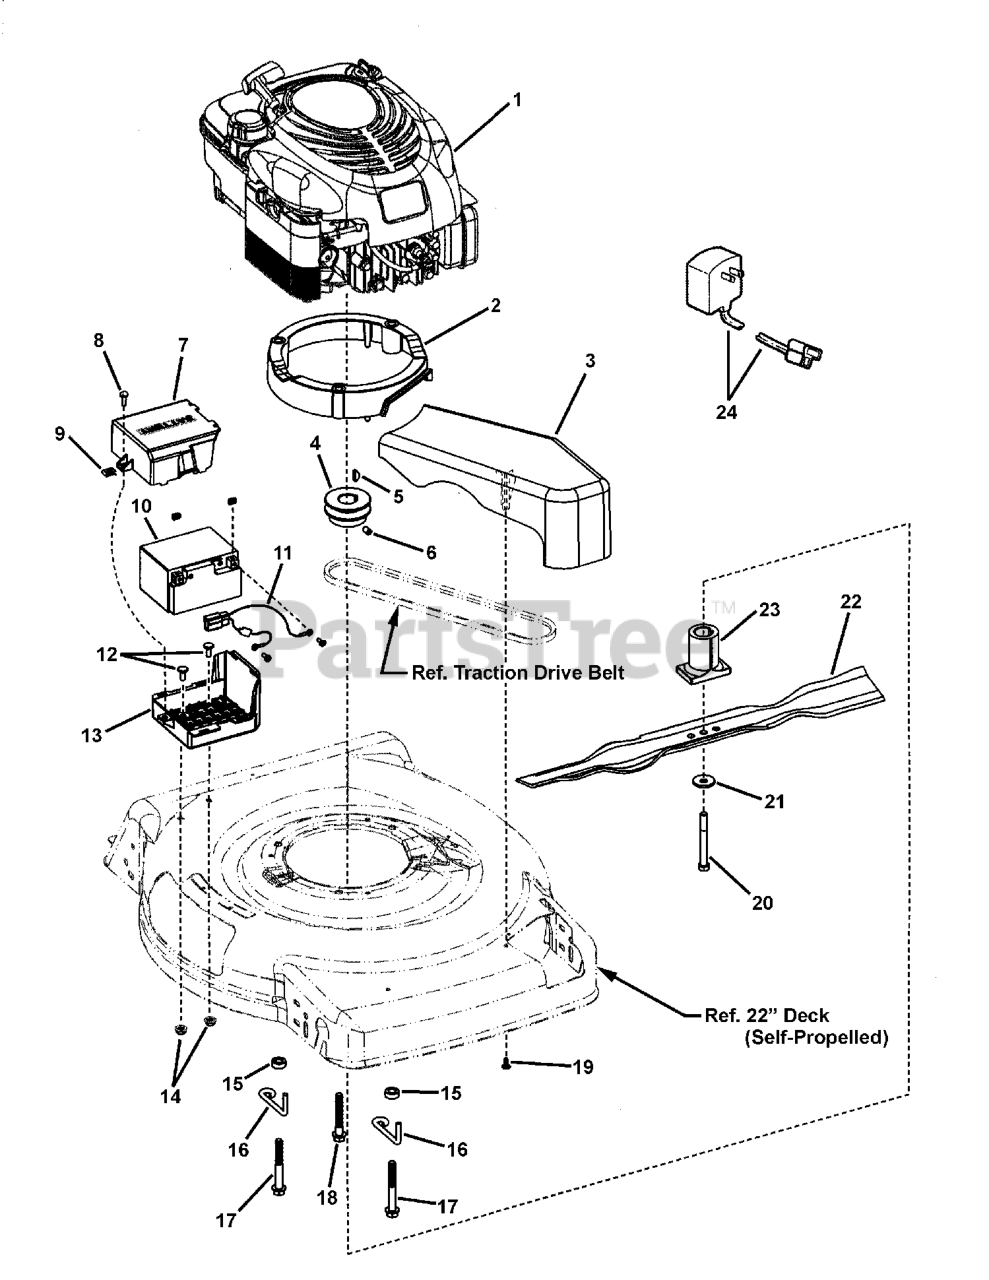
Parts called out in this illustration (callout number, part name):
1	ENGINE, B&S, 675 Series, ES, X, B3
2	ASSY, Engine Spacer (incl. 3 bushings, p/n 7101448)
3	COVER, Belt (Plastic)
4	PULLEY, Engine
5	KEY, #HP-506 Hi-Pro
6	SET SCREW, 5/16-18 x 1/2" Hex Recess
7	TOP, Battery Box, WBM
8	SCREW, #10-24 x 5/8" Hex Washer Face Self-Tap, GR 5
9	SPEED NUT, #10-24 Retainer w/Extrusion
10	ASSY, Battery w/Harness (incl. items 10 & 11)
11	HARNESS, Battery
12	BOLT, 1/4-20 x 5/8" Flat Head Square Neck, GR 5
13	BOTTOM, Battery Box, WBM
14	NUT, 1/4-20 Hex Flange Lock
15	SPACER, Belt Guide, 22" VS
16	BELT GUIDE, Engine, 22" VS
17	SCREW 3/8-16 x 3" Hex Washer Self-Tap
18	BOLT, 3/8-16 NS x 2-1/2" Hex Washer Face
19	SCREW, 4.8 x 1.59 x 13mm, Round Washer Head Hi-Lo (Torx)
20	BOLT, 3/8-24 x 3-1/4" Hex Head GR 8
21	WASHER, .38" I.D. x 1.183 O.D. Bellville
22	BLADE, 22", Walk Mower
23	BLADE HUB, 22" Deck
24	CHARGER, Battery
